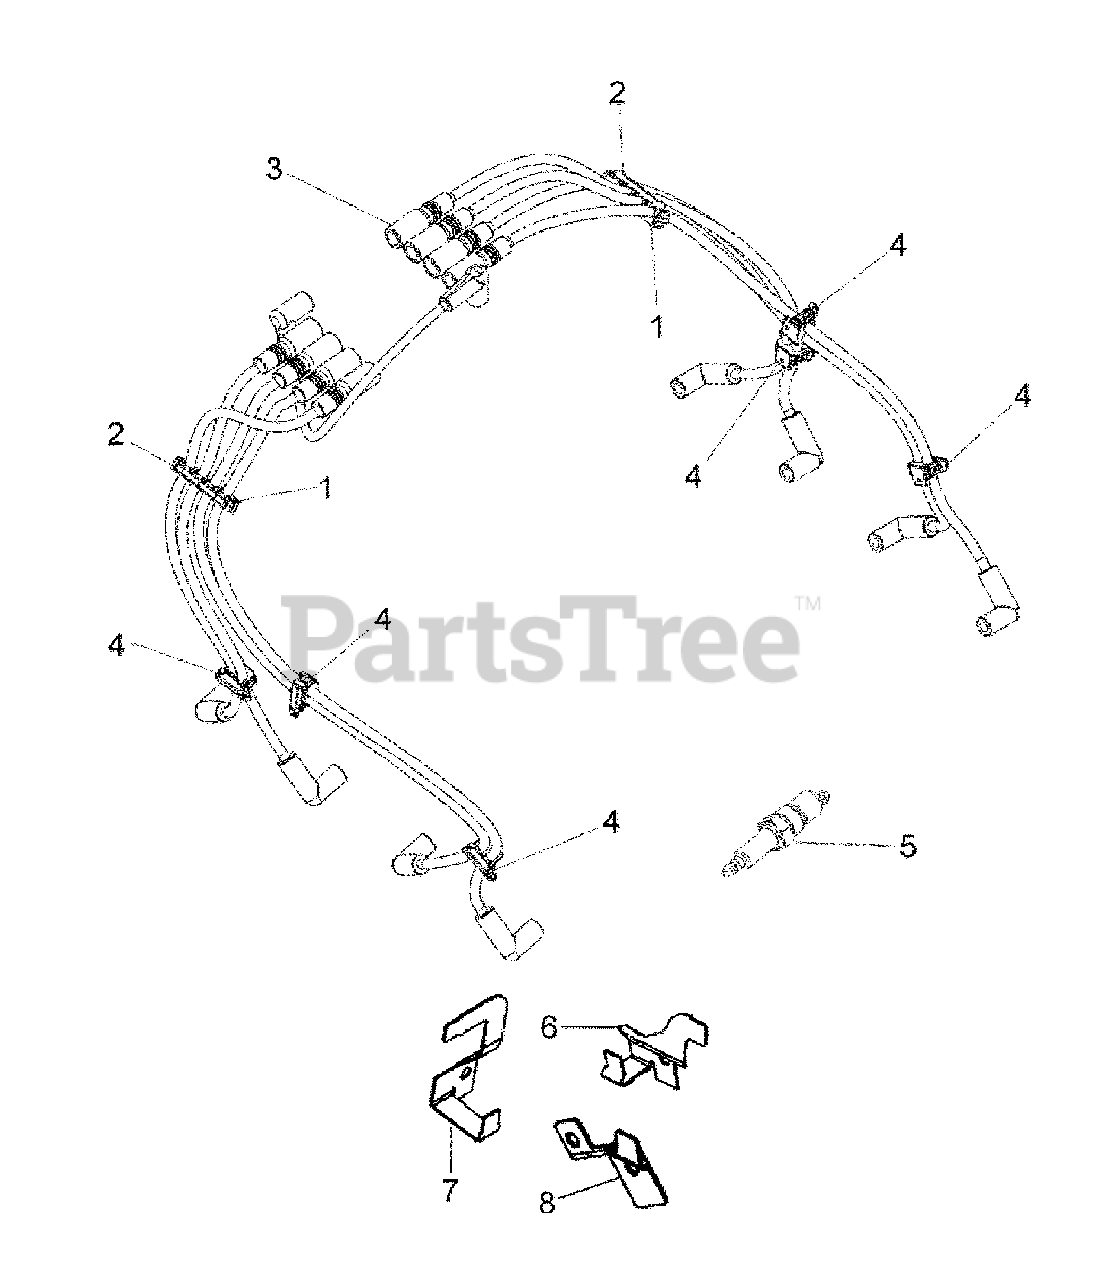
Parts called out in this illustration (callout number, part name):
1	COVER-CABLE CLIP
6	BRACKET
7	BRACKET
8	BRACKET
